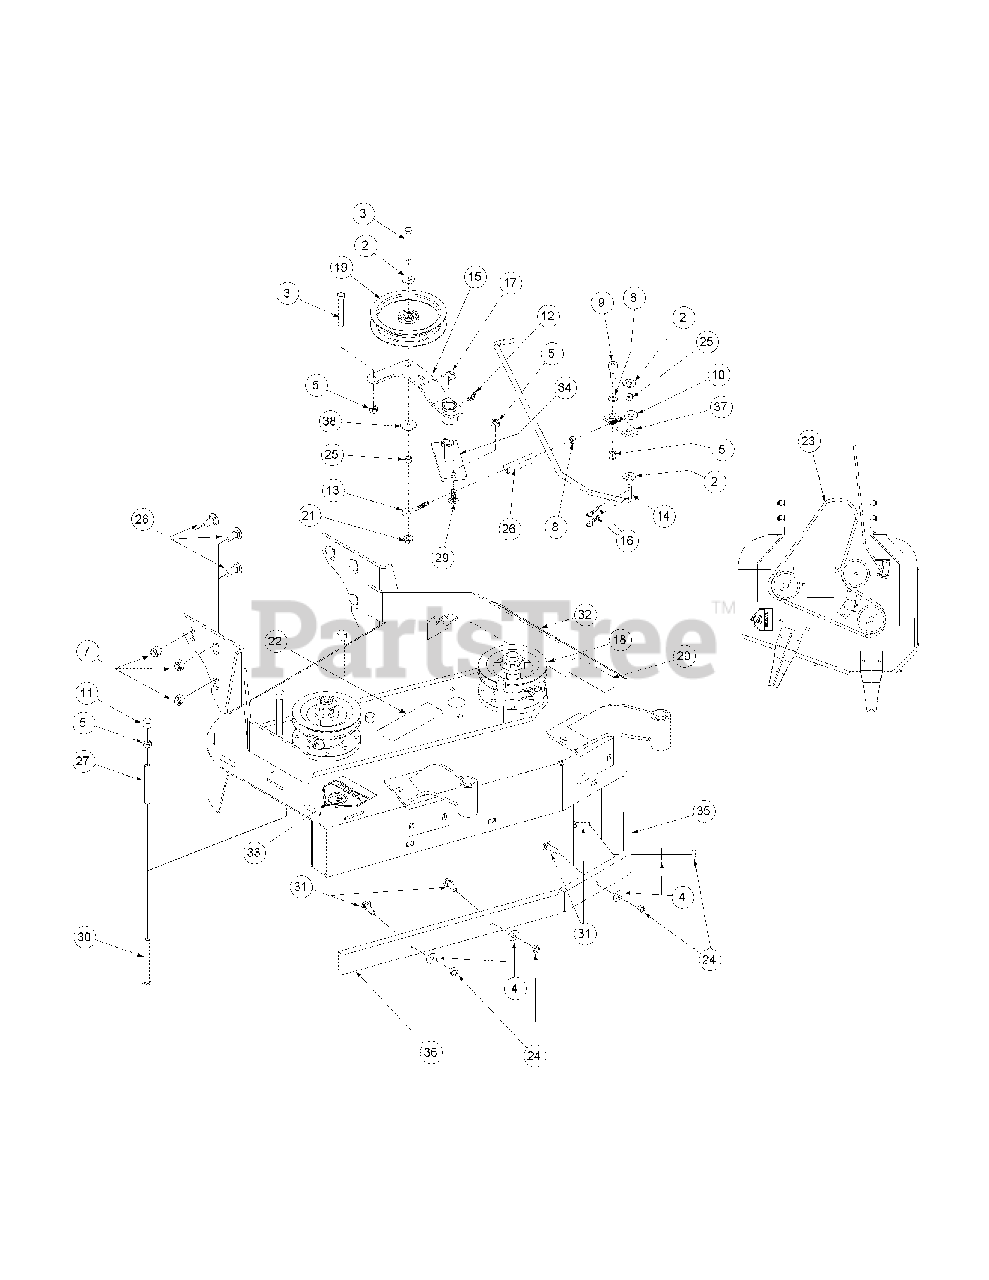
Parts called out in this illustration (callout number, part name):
1	Deck Stiffener
2	Flat Washer, 3/8 Zinc
3	Hex Cap Screw, 3/8-16 x 2.75
4	Flat Washer, 3/8 Zinc
5	Lock Nut, Nylon Insert, 3/8-16
6	Shim Washer
7	FlangeLock Nut, 1/2-13
8	Hex Nut, 5/16-18
9	Shoulder Bolt
10	Eye Bolt, Right Hand
11	Cap, Black Vinyl
12	Grease Fitting, 1/4-28 x 3/16
13	Eye Bolt, Left Hand
14	Blade Clutch, Rod
15	Idler Arm
16	Hair Pin, 3/8"-1/2"
17	E-Ring, Retainer
18	Deck Pulley
19	Idler Deck Take-up
20	Decal Rotating Blade
21	Hex Nut Flange Lock, 3/8-16
22	Decal, Warning Shield Missing
23	Belt Drive
24	Lock Nut, 3/8-16
25	Turnbuckle, Sleeve
26	Turnbuckle
27	Spacer, Belt Guide
28	Carriage Bolt, 1/2-13 x 1-1/4
29	Carriage Bolt, 3/8-16 x 2
30	Carriage Bolt, 3/8-16 x 4.5
31	Carriage Screw, 3/8-16 x 1.25
33	Decal, Danger, Hands and Feet
34	Idler Base
35	Bumper, Deck 32"
36	Bumper, Deck 32"
38	Washer, 1.25 x .411 x .100
